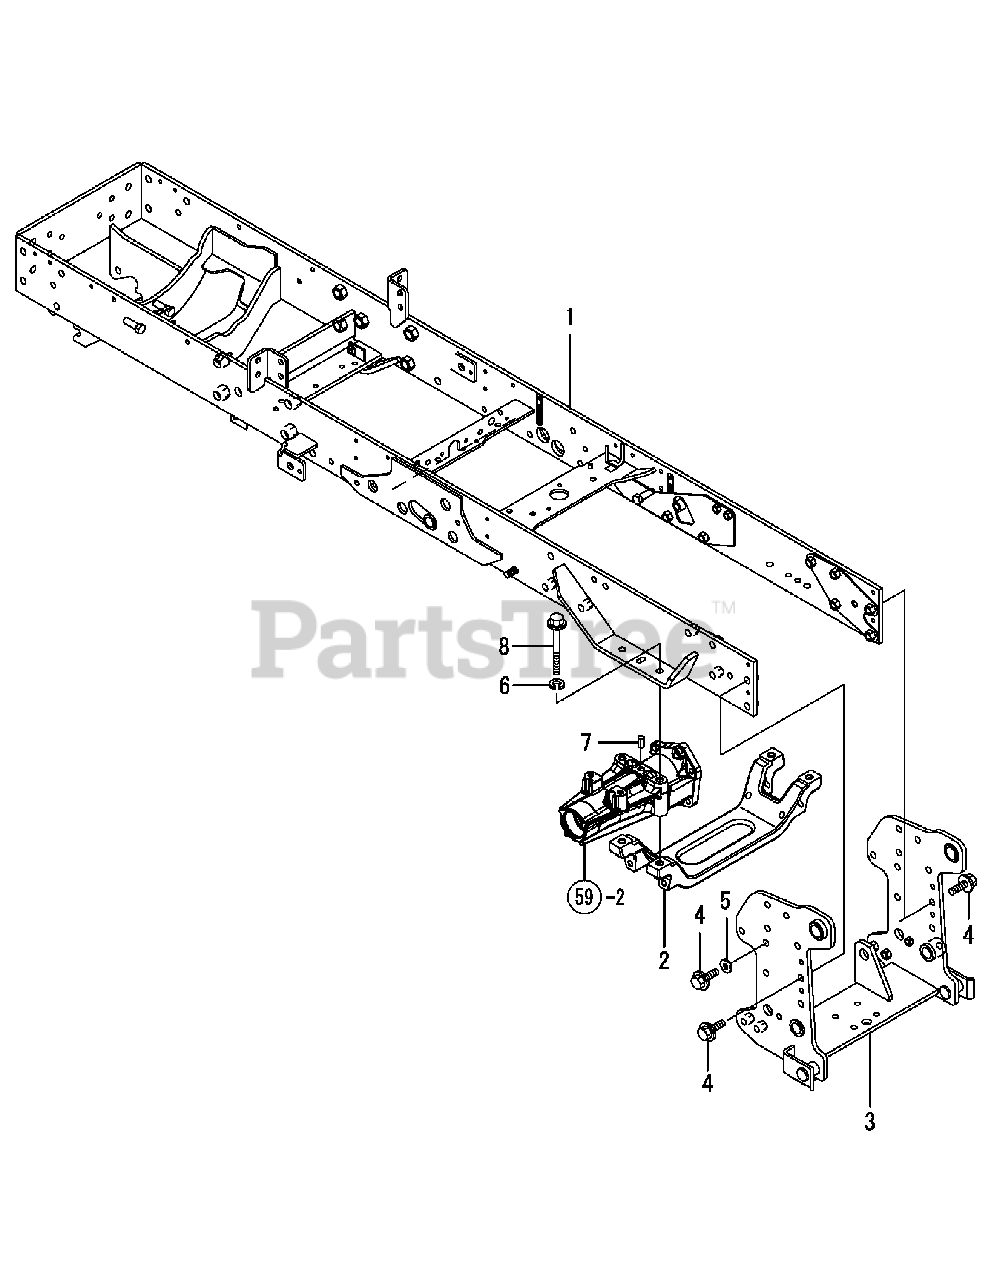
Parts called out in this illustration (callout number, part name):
1	FRAME M ASSY, TLB
2	BRACKET, TRANSMISSON
3	FRAME ASSY, LINK
5	WASHER 12, POLISHED
6	SPRING WASHER 12
7	SPRING PIN 10X20
8	BOLT M12X120 PLATED
